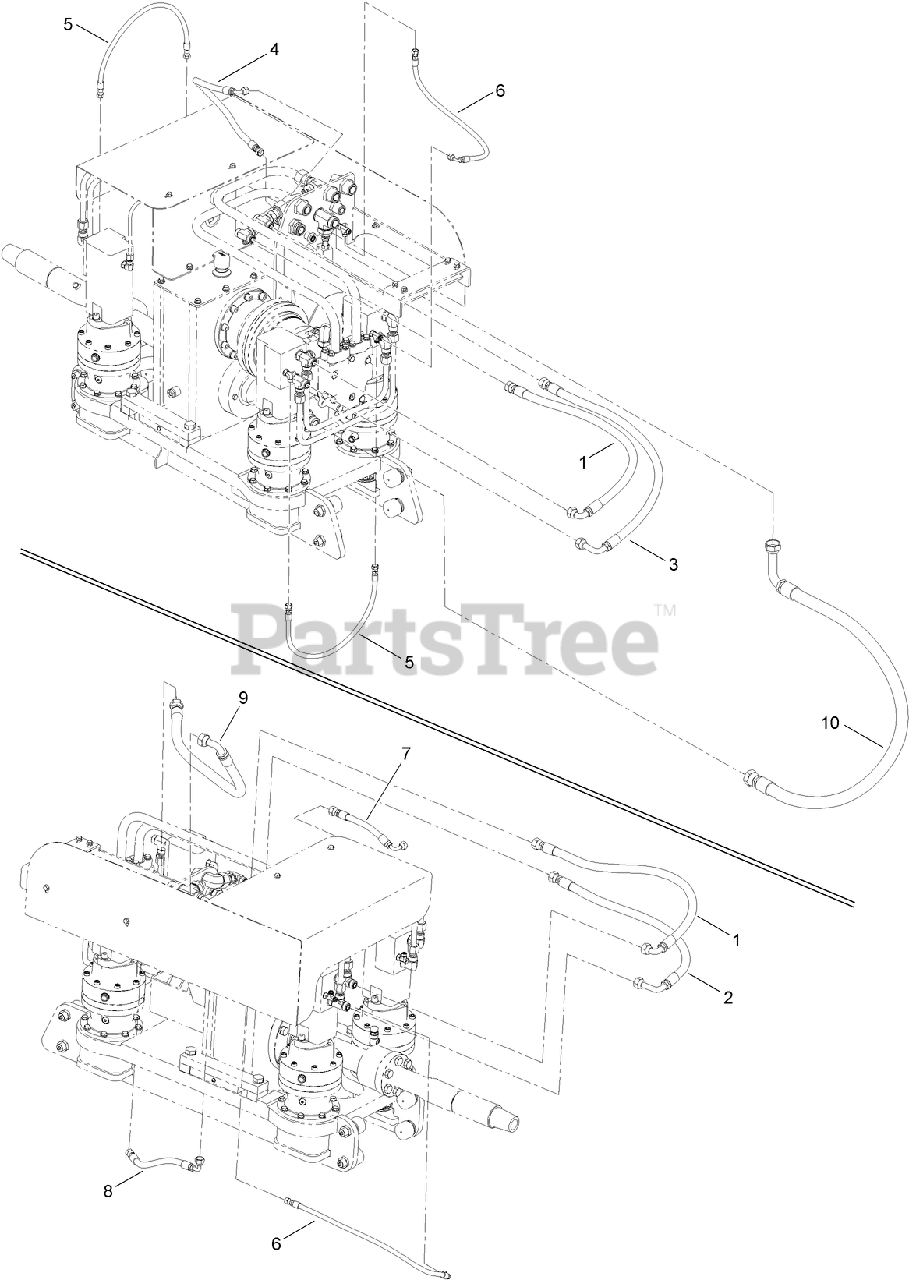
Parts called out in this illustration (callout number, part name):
1	HOSE ASM-HYD
2	HOSE ASM-HYD
3	HOSE ASM-HYD
4	HOSE ASM-HYD
5	HOSE ASM-HYD
6	HOSE ASM-HYD
7	HOSE ASM-HYD
8	HOSE ASM-HYD
9	HOSE ASM-HYD
10	HOSE ASM-HYD
